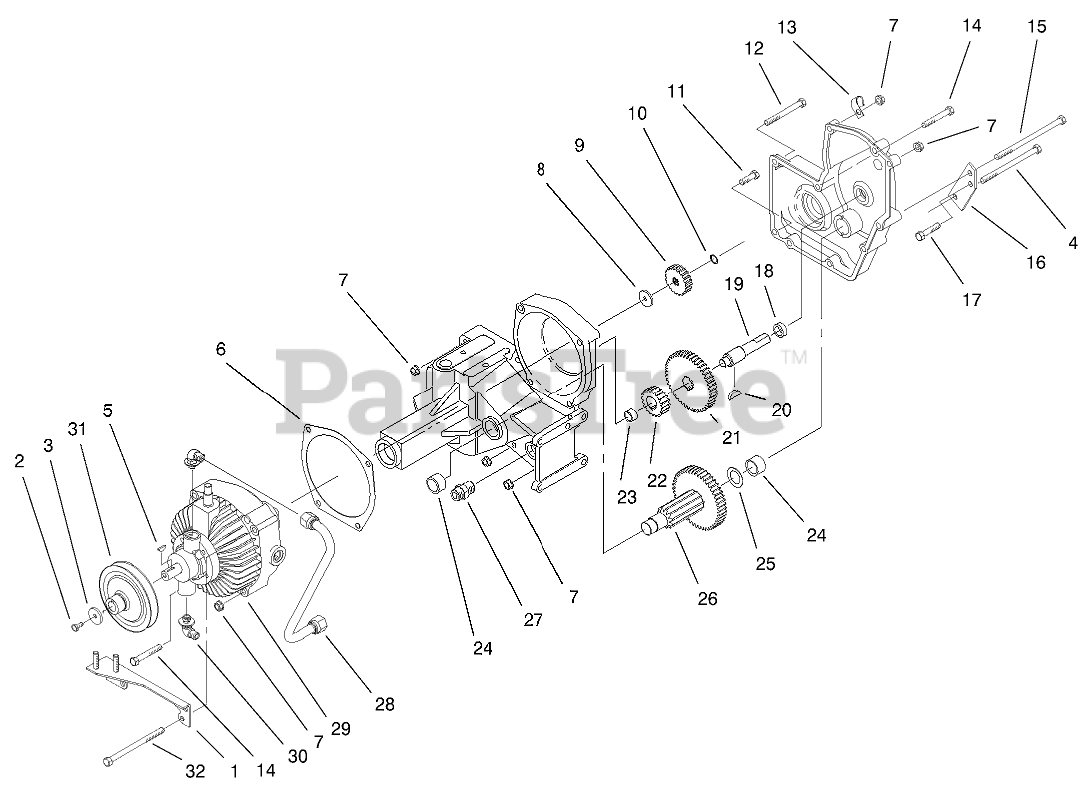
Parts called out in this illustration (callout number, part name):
1	ASSY-PLATE B
2	SCREW-HEX HD CAP
3	WASHER
4	SCREW-HH
5	KEY-WOODRUFF
6	GASKET
7	NUT-LOCK, NI
8	SPACER GEAR
9	GEAR 20 TEETH DRIVE
10	RING-SNAP, EXTERNAL
12	SCREW-HH
13	CLIP
15	SCREW-HH
16	BRACKET-BRAKEB
18	Race Thrust
19	SHAFT GEAR
20	Key
21	GEAR 46 TEETH
22	GEAR 20 TEETH
23	BEARING-NEEDLE
24	BEARING-NEEDLE
25	WASHER-THRUST
26	ASSY GEAR
26:1	GEAR 46T
26:2	PINION SHAFT
27	FITTING-TUBE
27	AXLE-REAR RH
28	ASSY-TUBE SUCTION
29	TRANSMISSION-PUMP
30	ELBOW
31	PULLEY
